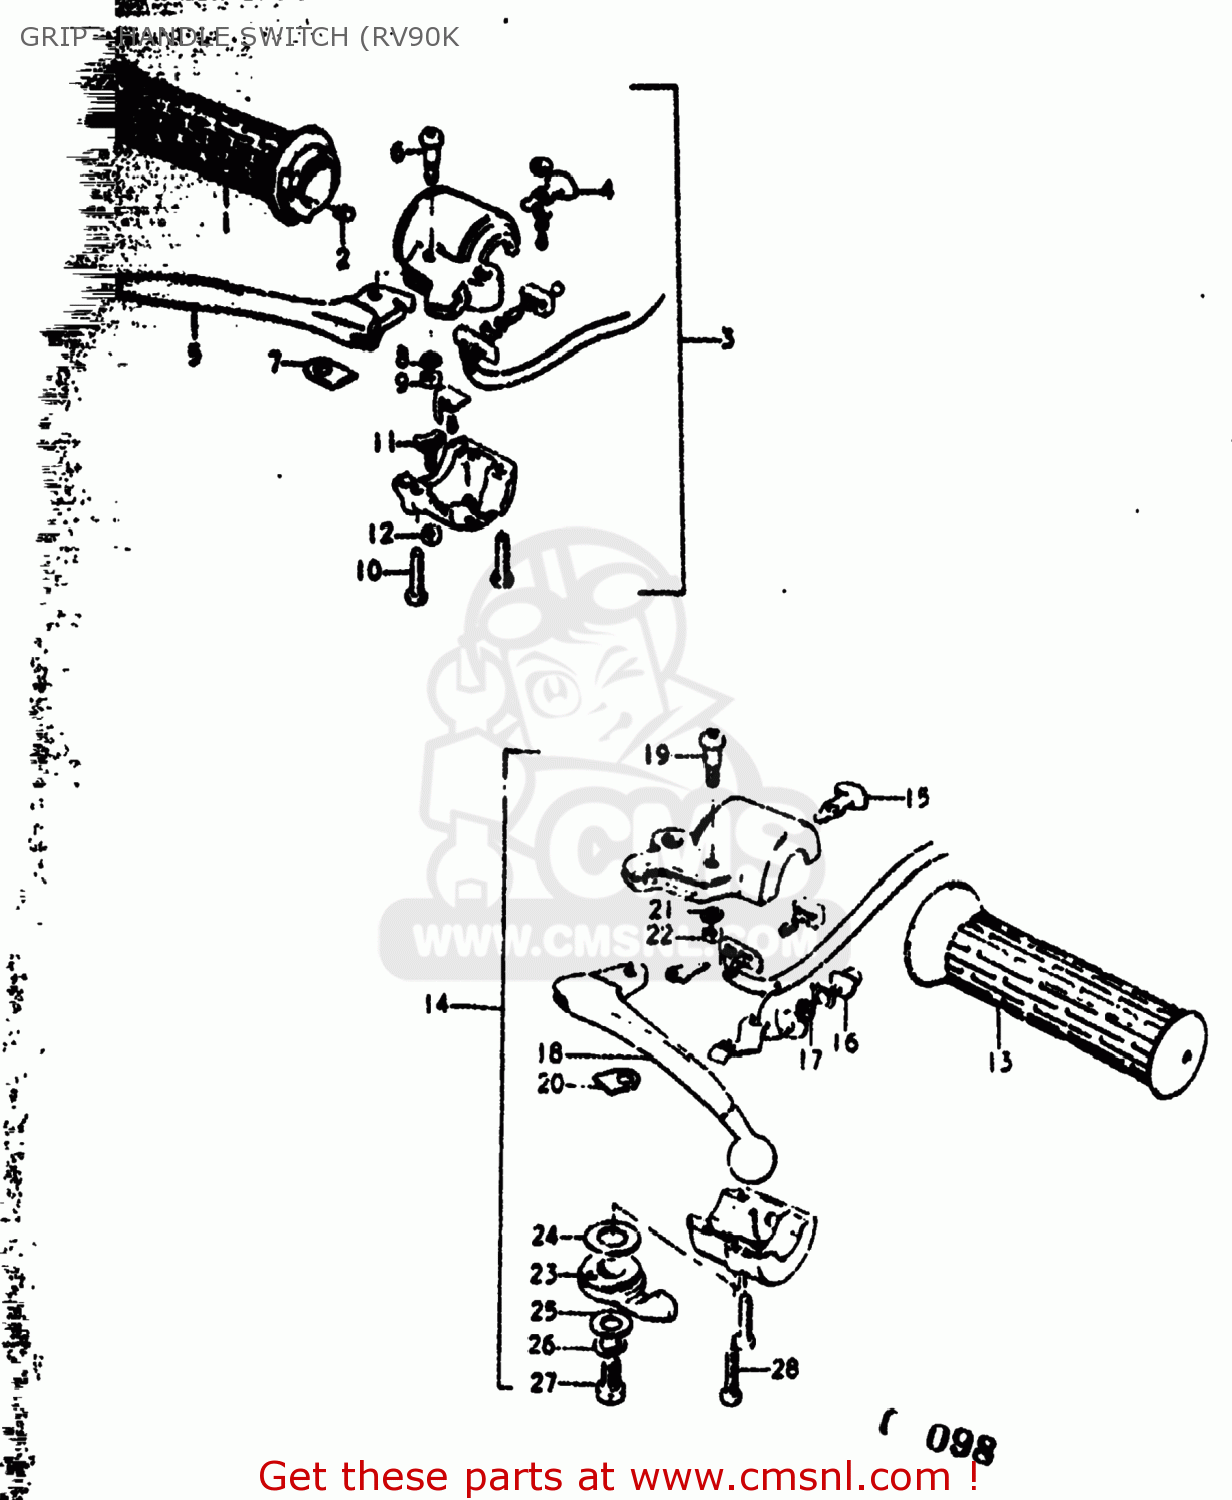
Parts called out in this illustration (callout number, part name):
1	GRIP,THROTTLE
2	PIECE,THROTTLE END
3	LEVER/SWITCH ASSEMBLY,BRAKE
4	KNOB,DIMMER SWITCH
5	LEVER,BRAKE
6	BOLT,LEVER
7	SPACER,LEVER
8	LOCK WASHER
9	NUT
10	SCREW
11	ADJUSTER,GRIP
12	NUT
13	GRIP
14	LEVER ASSEMBLY
15	KNOB,DIMMER SWITCH
16	BUTTON
17	SPRING
18	LEVER,CLUTCH
19	BOLT,LEVER
20	SPACER,LEVER
21	LOCK WASHER
22	NUT
23	LEVER,STARTER
24	WASHER,ADJUSTER
25	WASHER,STARTER LEVER
26	LOCK WASHER
27	BOLT
28	SCREW
